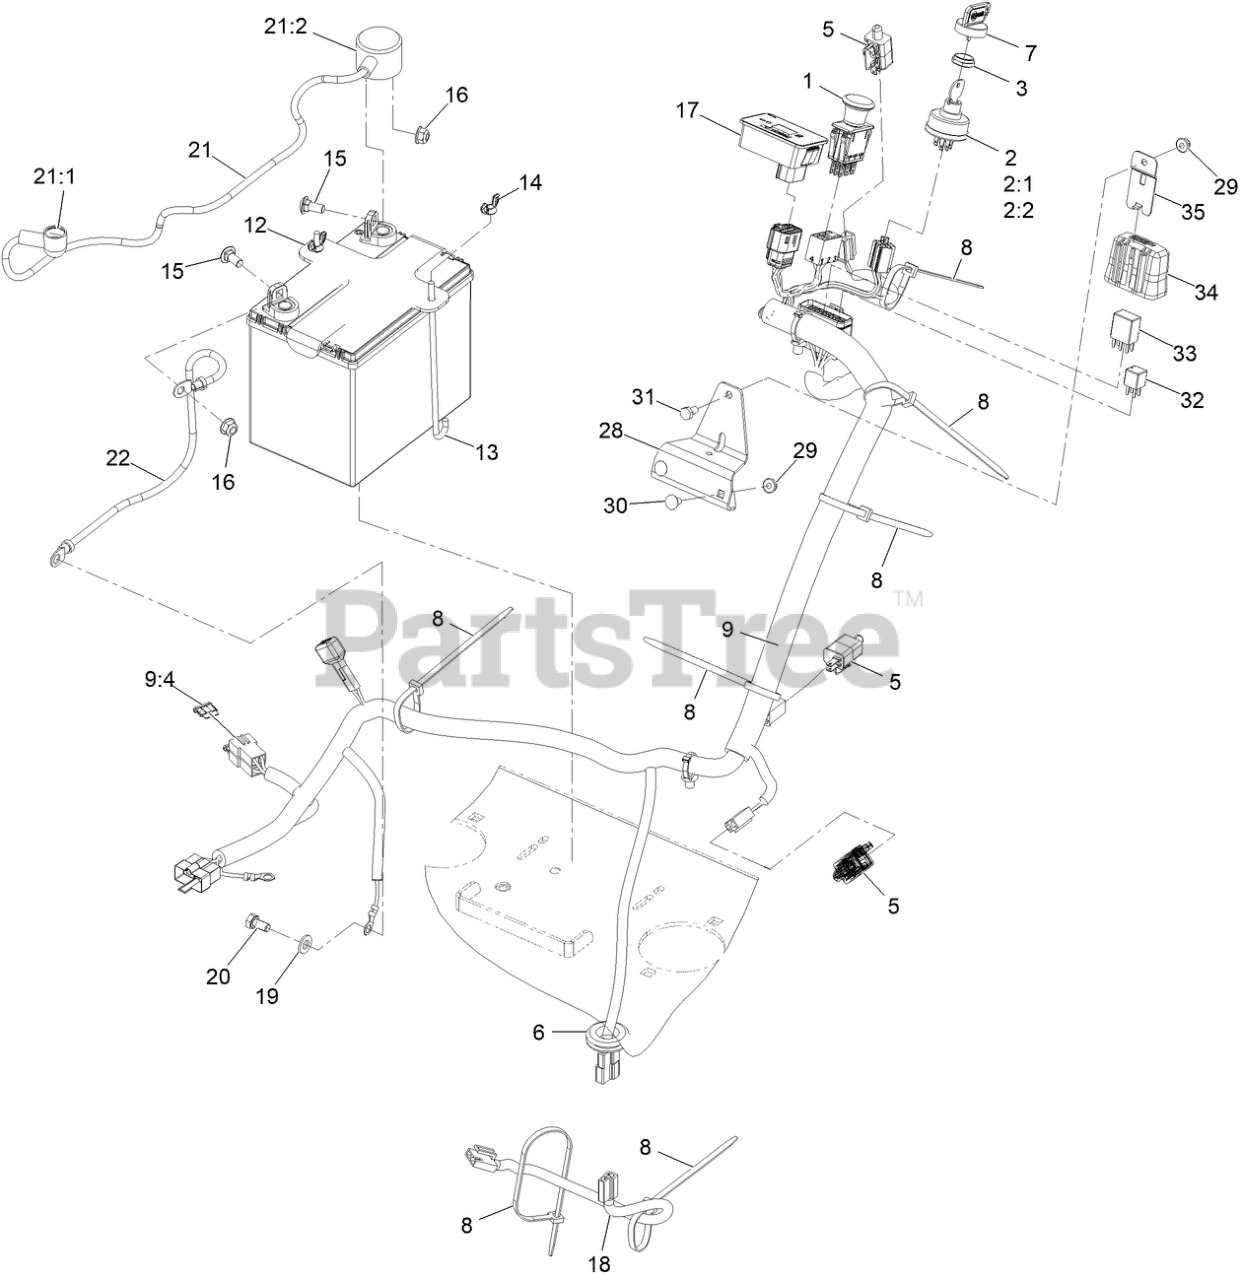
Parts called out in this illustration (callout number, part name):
1	SWITCH-PTO
2	SWITCH, KEY START
3	NUT-SWITCH, IGNITION
6	GROMMET
7	KEY-IGNITION
8	TIE-CABLE
9	HARNESS-WIRING
9:4	FUSE-BLADE TYPE, 20 AMP
12	BRACKET, BATTERY HOLD DOWN
13	BOLT-HOLDDOWN
14	WINGNUT
15	BOLT-CARR
16	NUT-HF, NI
17	MODULE-HOUR METER
18	HARNESS-CLUTCH PIGTAIL
19	WASHER-PLAIN
20	SCREW-HH
21	POSITIVE BATTERY CABLE AS
21:1	INSULATOR-SOLENOID
21:2	INSULATOR-BATTERY
28	BRACKET-MOUNTING, FUSEBLOCK
30	SCREW-CARR
31	SCREW-HH
32	RELAY-MICRO
33	RELAY-MICRO 280, SPDT
34	COVER-BLOCK, FUSE
35	CLIP-MOUNTING
